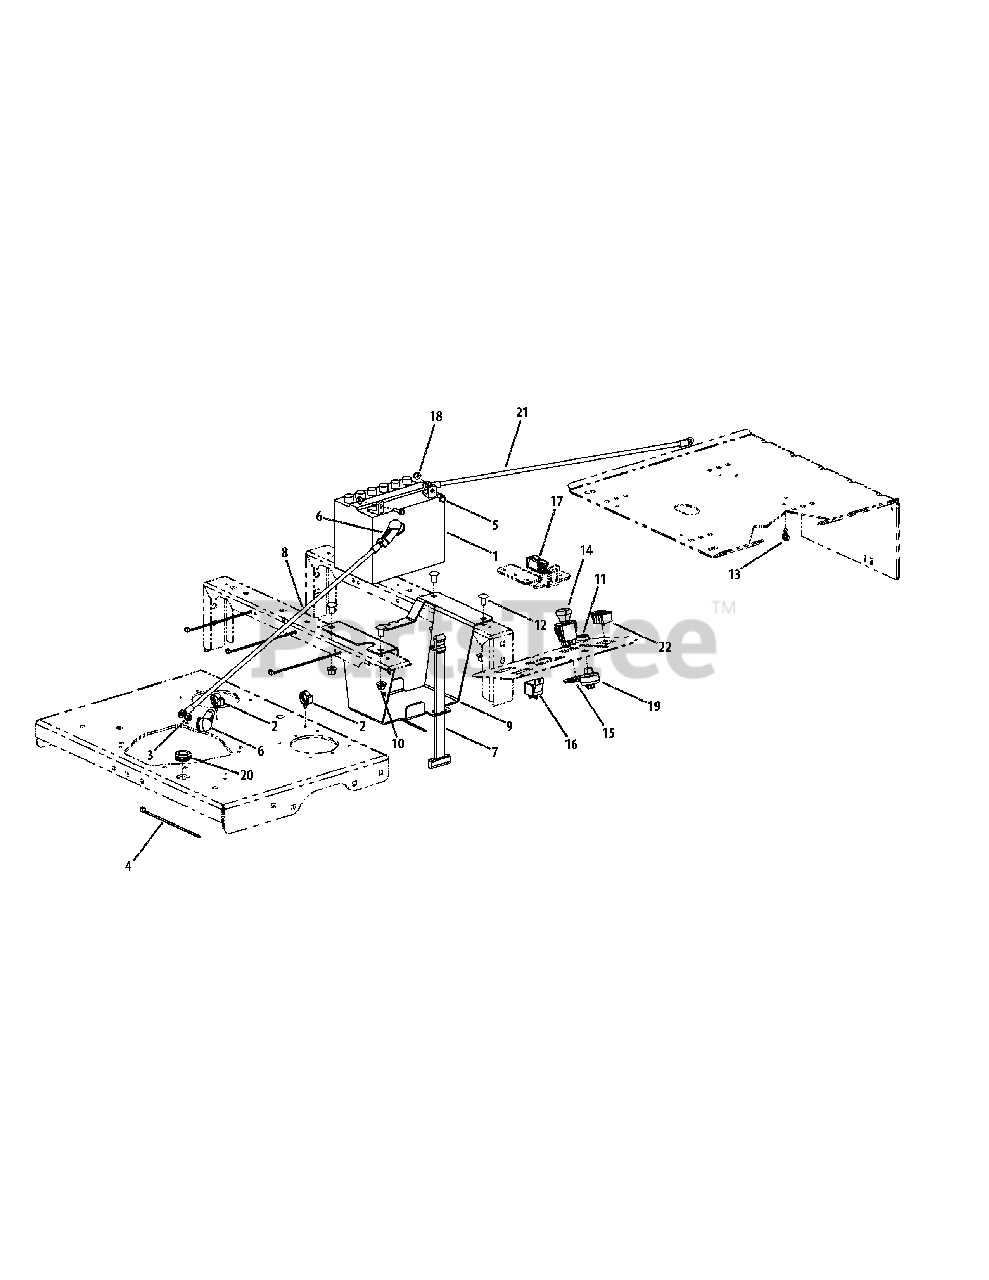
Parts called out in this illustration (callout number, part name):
1	Battery, 12V 225CCA 30 Min
2	Electrical Conduit Clip, 5/8
3	Nut, Flange Wiz - 31HP & 37HP
4	Tie, Cable, 3/16 x .05 x 7.4"
5	Screw, Hex, Cap, 1/4-20 x .75
6	Boot, 1" OD Rubber Battery-PST, Red
7	Strap, Battery
8	Cable, Battery Red, 42"
9	Battery Bracket
10	Hex Nut, Flange Lock, 3/8-16
11	Nut, W/Cap, 5/8-32 Ignition
12	Carriage Bolt, 3/8-16 x .75 Long
13	Electrical Conduit Clip, 3/8
14	Switch, Electric, PTO
15	Bracket, PTO Switch Retainer
16	Relay, 12V 40A
17	Switch, Safety N.O./N.C.
18	Hex Flange Lock Nut, 1/4-20
19	Switch, Ignition, 6 Pin
20	Grommet, .75 ID
21	Cable, Battery Black, 34"
22	Meter, Hour
